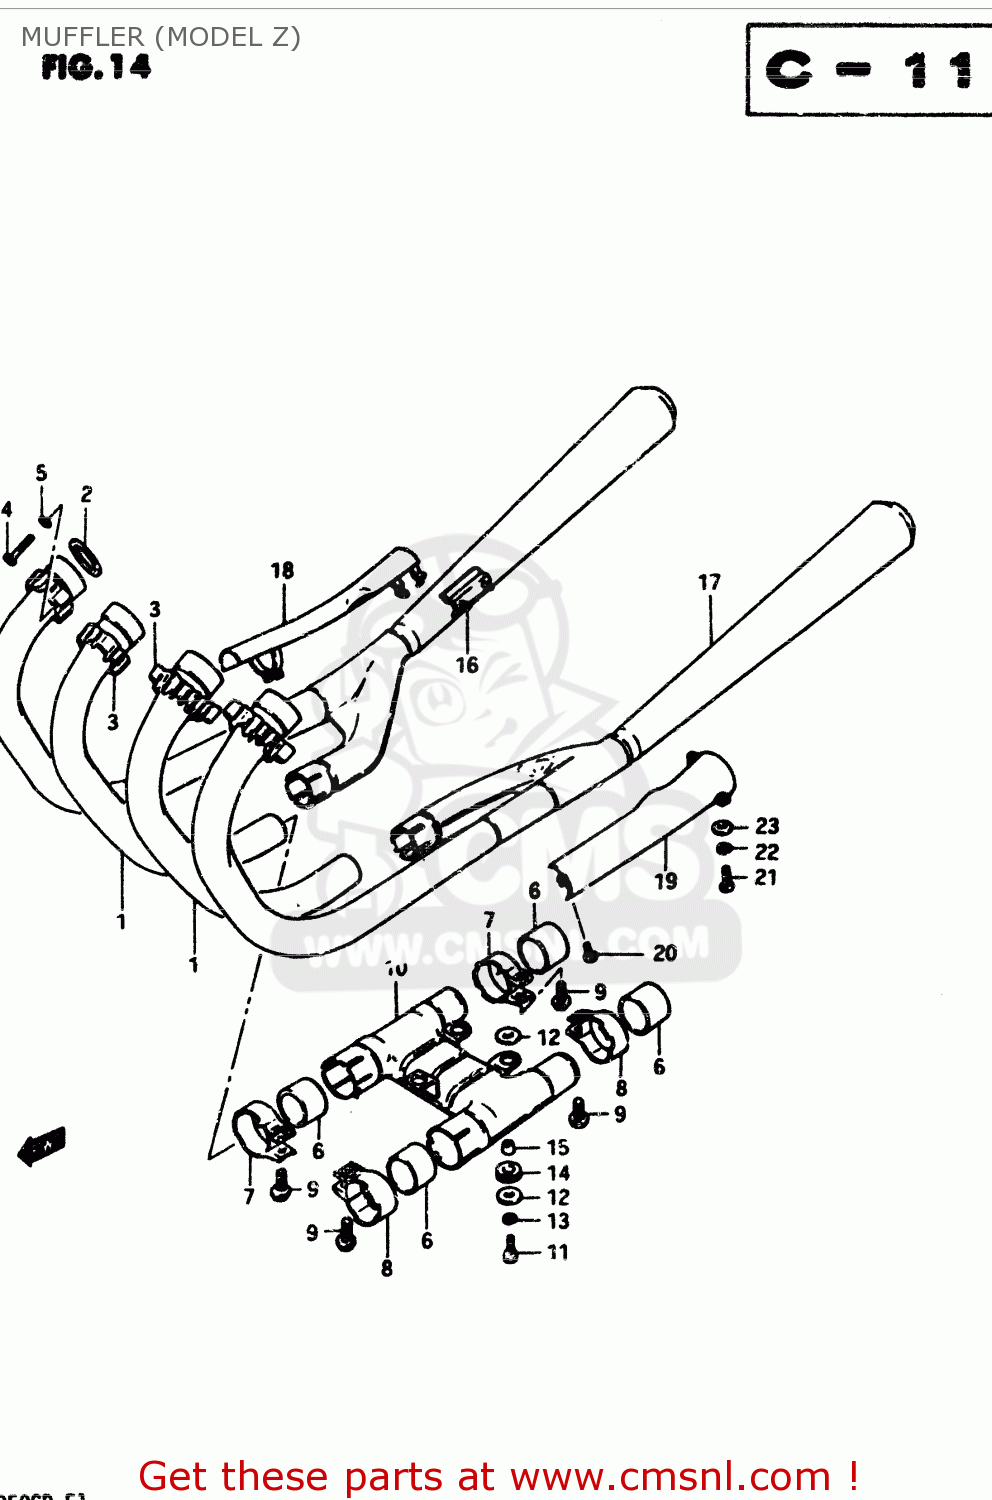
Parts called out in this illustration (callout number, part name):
1	PIPE,CENTER EXHAUST
2	GASKET,EXHAUST PIPE (NAS)
3	CLAMP,EXHAUST PIPE
4	BOLT
5	LOCK WASHER
6	CONNECTOR,MUFFLER
7	CLAMP,MUFFLER CONNECTOR,R
8	CLAMP,MUFFLER CONNECTOR,L
9	BOLT
10	BODY,PREMUFFLER
11	BOLT
12	WASHER (6.5X24X1.6)
13	LOCK WASHER
14	CUSHION
15	SPACER(6.5X10.5X6.5)
16	MUFFLER ASSEMBLY
17	MUFFLER ASSEMBLY
18	COVER,MUFFLER
19	COVER,MUFFLER,LEFT
20	SCREW
21	SCREW
22	LOCK WASHER
23	WASHER
